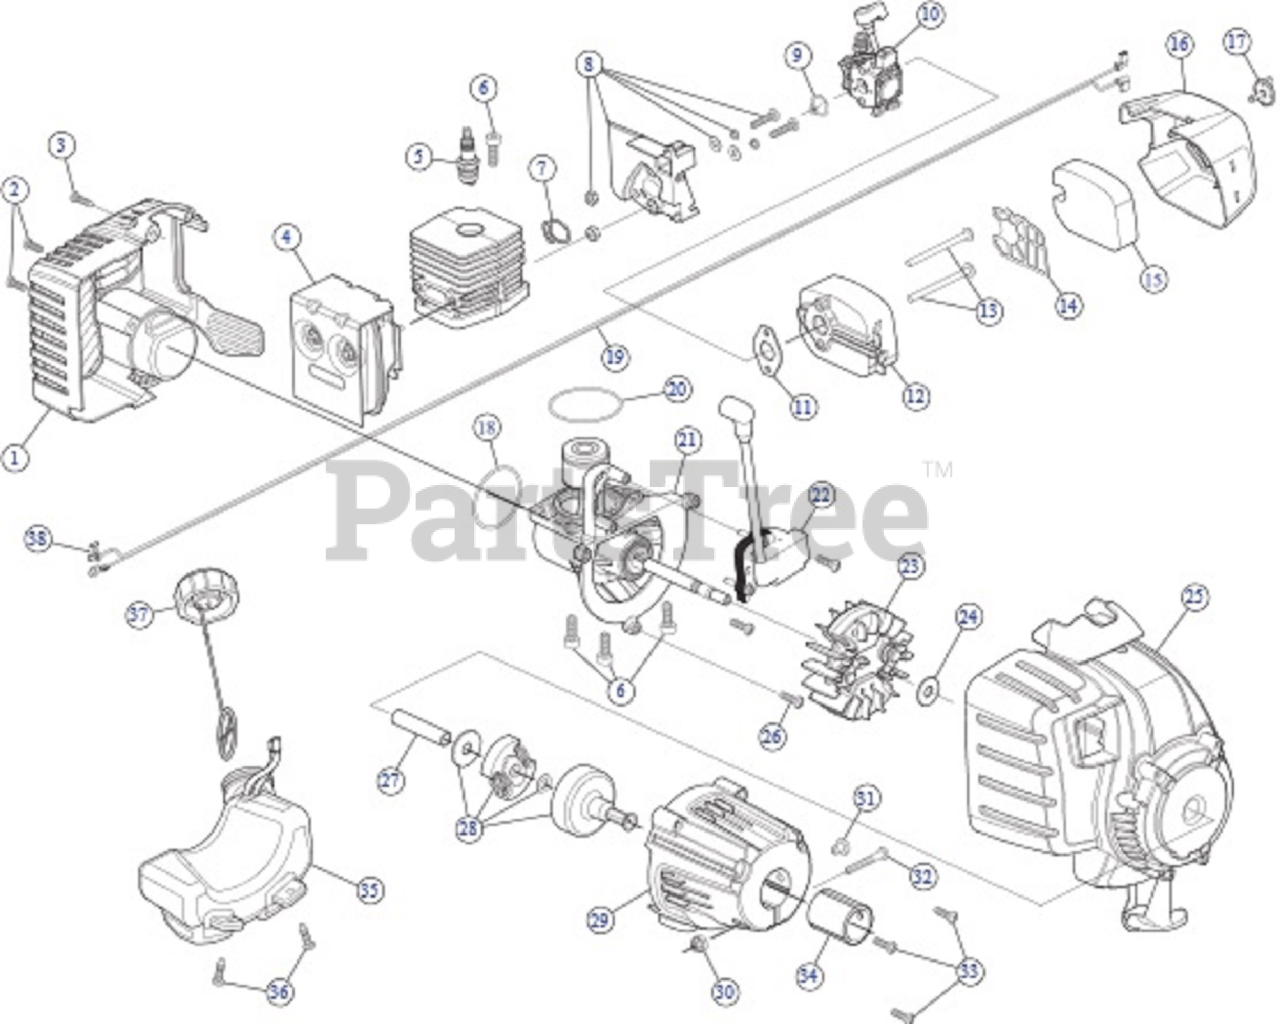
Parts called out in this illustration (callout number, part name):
1	Rear Housing (Incl. 1, 2 & 19)
2	Screw
5	Spark Plug
8	Insulator Assembly (Incl. 8 & 10)
10	Carburetor
12	Air Cleaner Base
16	Air Cleaner Cover
21	Shortblock (Incl. 6, 7, 21 & 23)
25	Starter Housing
26	Screw
28	Clutch Assembly
29	Clutch Cover
32	Screw
34	Spacer, Rubber
35	Fuel Tank (Incl. 37 & 38)
36	Fuel Tank Screw
37	Fuel Tank Cap
